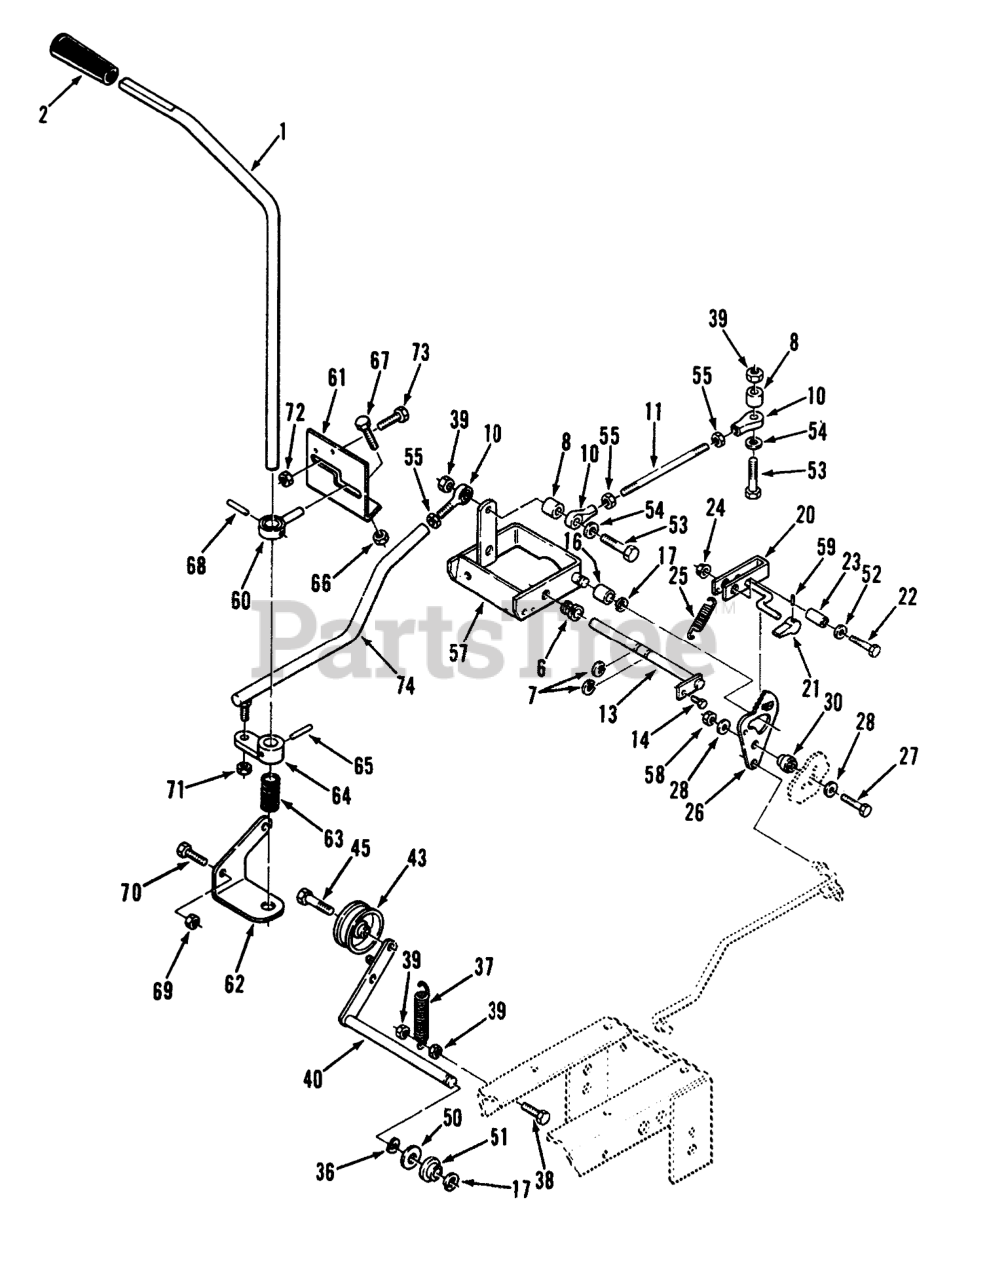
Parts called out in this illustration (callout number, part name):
1	ROD-MOTION CONTROL
2	Knob-Motion Control
6	NYLINER BUSHING
7	SCREW-HH
8	Spacer
10	ROD END, 1/4-28
11	ROD-CONTROL
13	ASSY-ROD CAM PIVOT
14	SCREW
16	BEARING-CAM RETURN
17	RING-RETAINING, EXTERNAL
20	Lever-Parking Brake
21	KNOB-PARKING BRAKE
22	SCREW-HH
23	SPACER
24	LOCKNUT-FLANGE
25	Spring
26	Cam Plate
27	SCREW-HH
28	WASHER-FLAT
30	Spacer
36	WASHER-WAVE
37	SPRING-EXTENSION
38	SCREW-HH
39	NUT-LOCK, NI
40	WLDMT-IDLER ARM
43	PULLEY-IDLER
45	BOLT-SPECIAL HEX
50	Washer
51	BUSHING-FLANGED
52	WASHER-FLAT
53	SCREW-HH
54	WASHER-FLAT
55	NUT-JAM
57	Cam Comtrol
58	NUT-LOCK, NI
59	PIN-SPIROL 3/32X5/8
60	GUIDE-CONTROL
61	BRKT-CONTROL
62	Bracket-Control
63	SPRING-COMPRESSION
64	ARM-CONTROL
65	PIN-SPECIAL
66	NUT-LOCK, NI
67	SCREW-HH
68	SPIROL PIN 7/32X7/8
69	NUT-LOCK, NI
70	SCREW-HH
71	NUT-LOCK
72	NUT-LOCK, NI
73	SCREW-HH
74	ASSY-ROD & BALL JOINT
